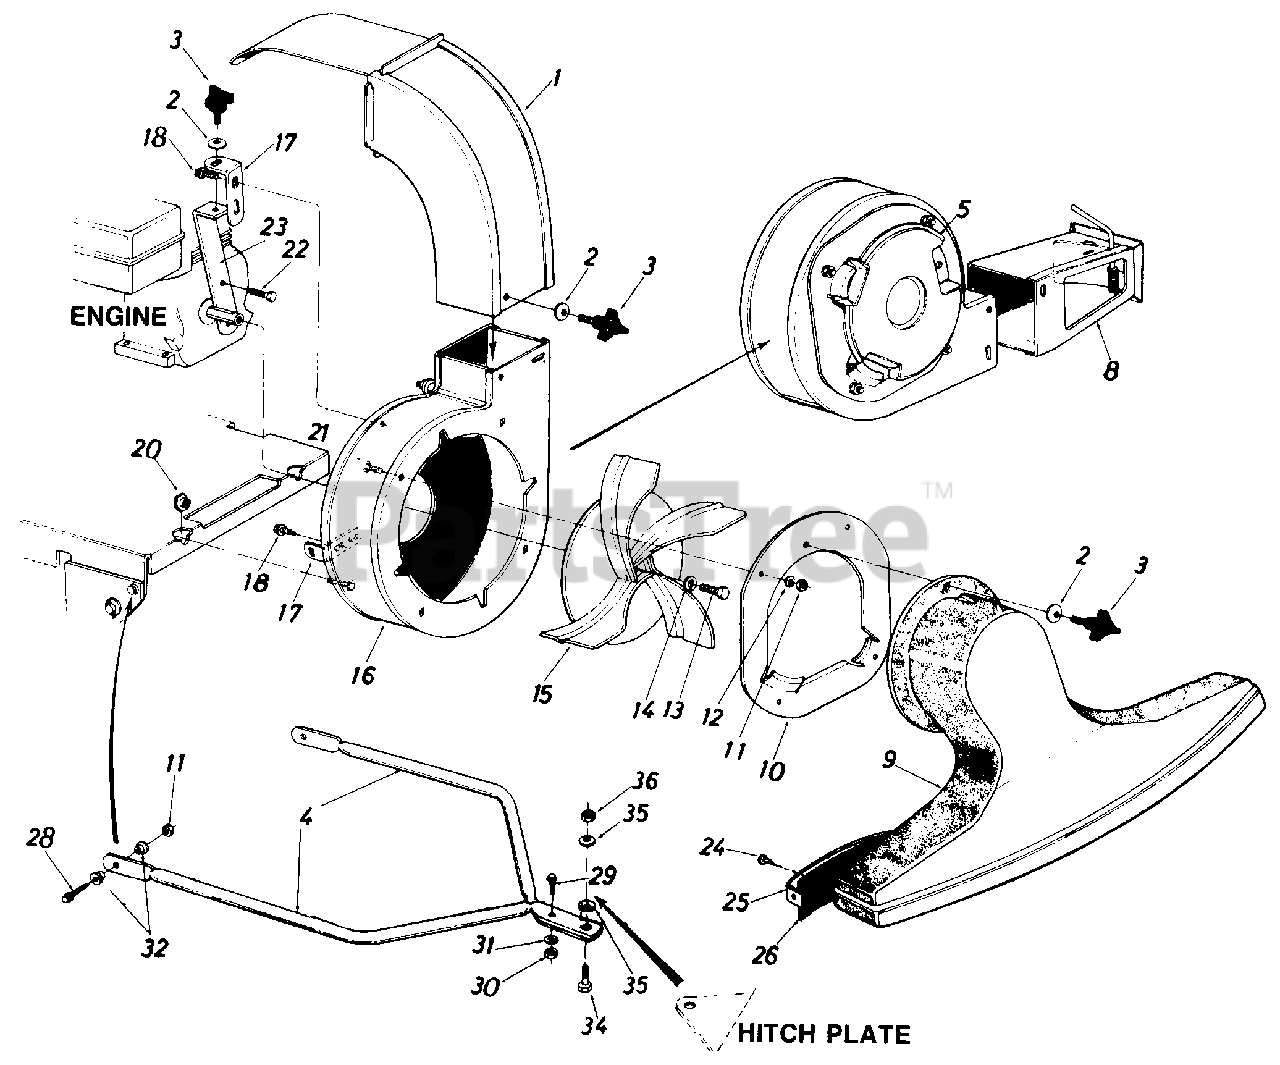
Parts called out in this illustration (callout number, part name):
3	3-Arm Thumb Scr. 5/16-18 x .75" Lg.
10	Nozzle Plate Ass'y.
11	Hex Nut 5/16-18 Thd.
12	L-Wash. 5116" I.D.
13	Hex Bolt 3/8-24 x 1.25" Lg.
14	L-Wash. 318" I.D. H.D.
15	Air Vane Plate Ass'y.
20	Hex Shoulder Nut .50 I.D.
21	Carriage Bolt 5/16-18 x .62" Lg. *
22	Hex Locking Bolt 5/16-24 x .75" Lg.
28	Hex Bolt 5/16-18 x 1.00" Lg.
29	Truss Mach. Scr. 1/4-20 X .75" Lg. *
30	Hex Nut 1/4-20 Thd.*
31	L-Wash. 114" I.D.*
32	Shoulder Spacertt
34	Shld. Bolt .496 Dia.
35	Belleville Wash. .39" I.D. x 1.12" O.D.
36	Hex Jam L-Nut 3/8-26 Thd.
